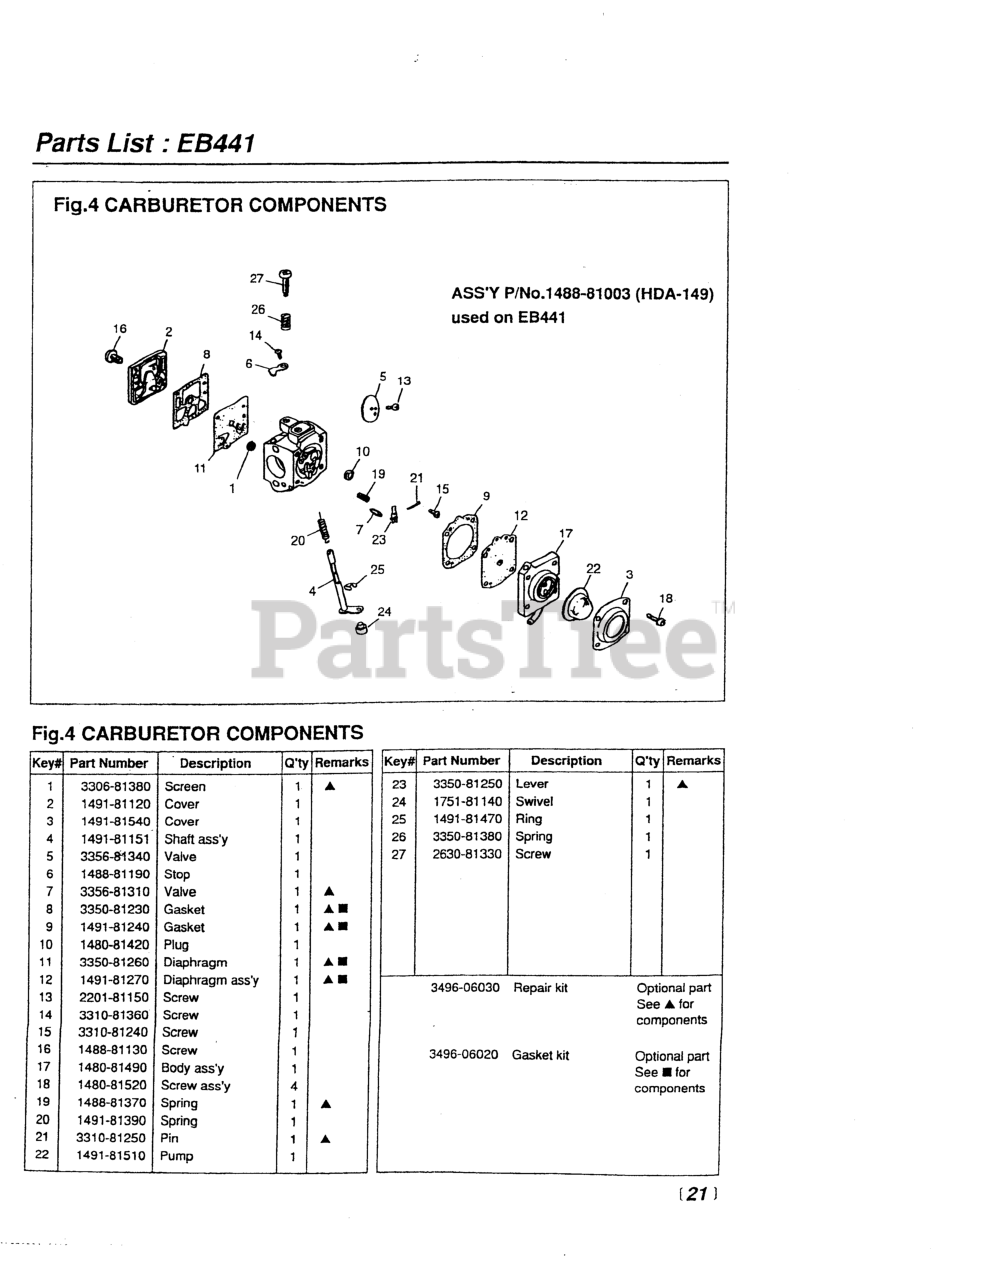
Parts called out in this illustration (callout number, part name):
2	COVER, PUMP
3	COVER, PUMP
4	SHAFT ASSEMBLY
5	VALVE, THROTTLE
7	VALVE, INLET
8	KIT ONLY
9	KIT ONLY
10	PLUG, WELSH
11	KIT ONLY
16	SCREW (RPLS 1491-81130)
17	BODY ASSY (RPLS 1491-81490)
18	SCREW (REPLACES 1491-81350)
20	SPRING
21	PIN, METERING LEVER
22	PUMP, PRIMER
23	KIT ONLY
26	SPRING, IDLE
NI	CARBURETOR (RPLS -81002)
NI	REBUILD KIT, EB430/440
NI	EB430/40 DIA/GASK KIT
